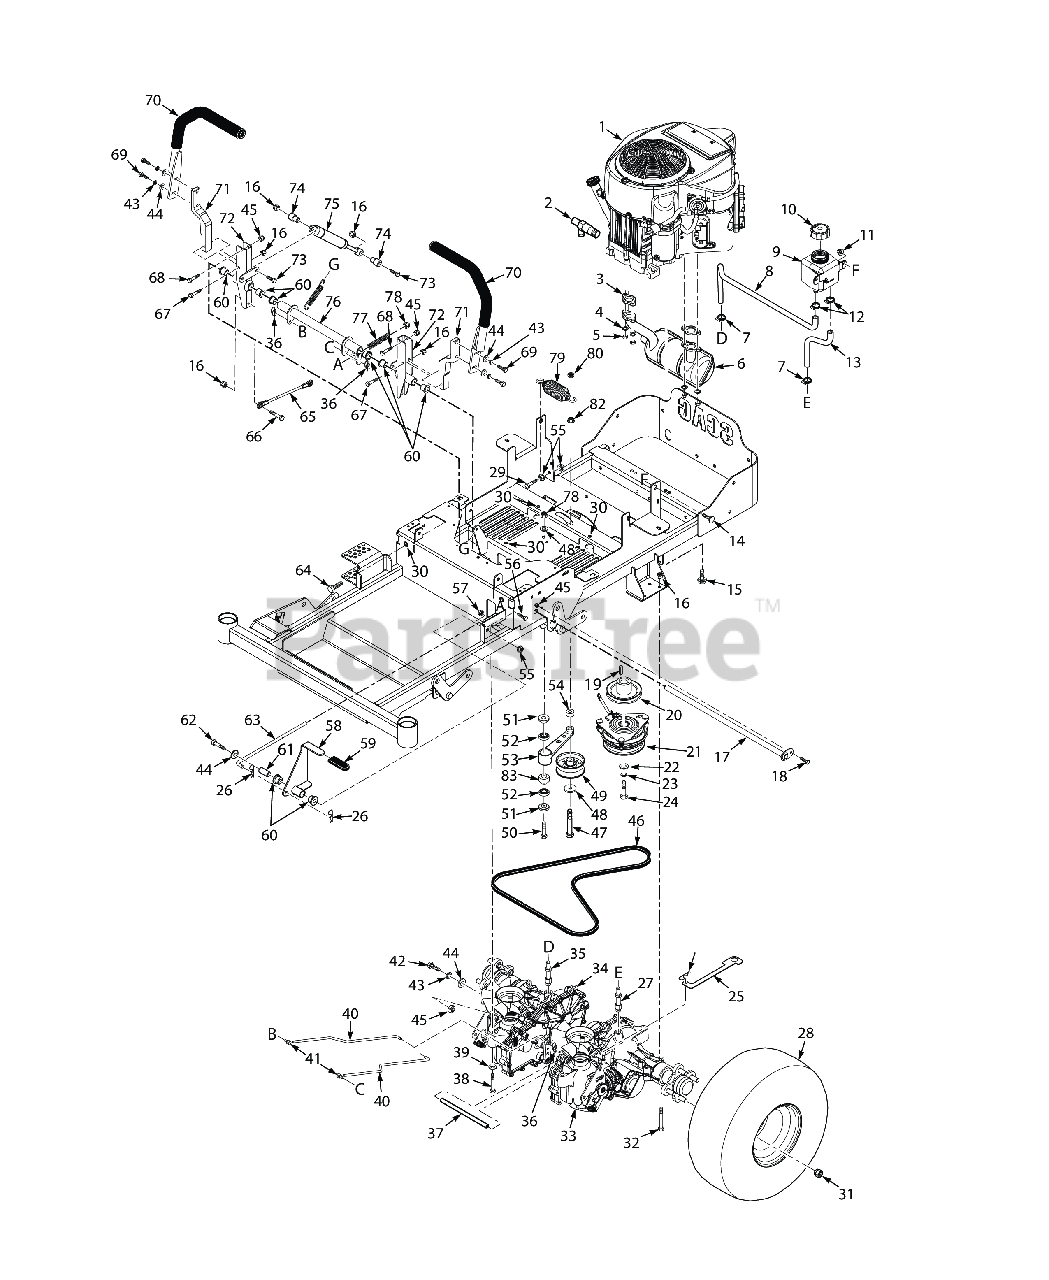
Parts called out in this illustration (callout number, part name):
1	Engine, Kawasaki - FR600V
2	Oil Drain, Kawasaki
3	Gasket, Exhaust
4	Nut, M8 x 1.25 Hex Special
5	Lockwasher, M8 Spring (Kawasaki)
6	Muffler, Kawasaki FR/FS600V
7	Clamp, .69" Max. / .25" Min. Dia.
8	Hose, RH Transaxle
9	Reservoir Assembly
10	Cap, Hydraulic Tank
11	Nut, Flanged Elastic Stop 1/4-20
12	Clamp, Cable 3/4" I.D.
13	Hose, LH Transmission
14	Serr. Fl. Hex Head CPSCR, 1/4-20 x 3/4"
15	Bolt, Hex Head Self-Tap 3/8-16 x 1-1/4" (Kohler x3 - 25EFI, Kohler x4 - 29EFI)
16	HEX NUT, ELASTIC STOP LOCK, 5/16-18
17	Shaft Weldment, Control Arm
18	BOLT, HEX HEAD, 1/4-20 X 5/8
19	Key, 1/4 x 1/4 x 1.25" Pulley Mtg.
20	Pulley, 4-1/2" Dia. - 1" Bore
21	Electric Clutch Assembly
22	Flatwasher, 7/16-.469 x 1.75 x .25 (48, 52)
23	Lockwasher, 7/16� Spring
24	Bolt, Hex Head 7/16-20 x 3" w/t Patch
25	Lever, Dump Valve
26	HAIR PIN, .08 DIAMETER X 1-3/16"
27	Fitting, 9/16" O-Ring x 3/8" Hose
28	Wheel Assembly, 20 x 8.0-10
28	Rim W/Valve Stem 10 x 5.0
28	Tire, 20 x 8.0-10
29	Bolt, Hex Head 3/8-16 x 1-1/2" Grade 8 Black
30	Threaded insert, Hex Head (Pressed)
31	Wheel Nut, 1/2-20 x 13/16
32	Bolt, Hex Head, 5/16-18 x 2.75 Zinc.
33	Transaxle, LH- ZT-2800
34	Transaxle, RH- ZT2800
35	Fitting, O-Ring 9/16 Hose
36	Pin, Rue Cotter 3/8" Diameter
37	Spacer, Axle
38	BOLT, HEX HEAD, 5/16-18 X 2-1/4
39	Flatwasher, 5/16-.375 x .875 x .083 (35BV & 37BV-EFI)
40	Rod, Brake
41	Joint, Swivel
42	Bolt, Hex Head, 1/4-20 x 1-1/2"
43	Lockwasher, 3/8" Spring, Kawasaki FX / FS
44	Flatwasher, 3/8" Special (.391 x .938 x .105)
45	HEX, NUT, ELASTIC STOP LOCK, 1/4-20
46	Belt, Transmission SZL-36
47	Capscrew, Hex Head 3/8-16 x 3-3/4"
48	Flatwasher, 3/8 (.391 x .938 x .105 HD) Grade 8
49	Pulley, 3-1/2" Dia.
50	Bolt, Hex Head 3/8-16 x 3" - 52"
51	Spacer, Controls
52	BEARINGS, BALL, NEUTRAL RETURN
53	Trans. Idler Arm Assy. (Includes 24, 79)
54	Spacer, Idler Pulley - SFZ61
55	NUT, 3/8-16 SERRATED FLANGE HEX HEAD
56	Bolt, Hex Head 5/16-18 x 1-1/2" (Right Front Engine Mounting, Briggs and Kohler Only)
57	NUT, 1/4-20 SERRATED FLANGE HEX HEAD
58	Brake Lever Assembly, SZL-36
59	Grip, Brake Handle
60	Bearing
61	Pivot, Brake Lever
62	Capscrew, Hex Head 3/8-16 x 2-1/2"
63	Rod, Upper Brake Linkage
64	Bolt, Hex Head 3/8-16 x 3.0
65	Linkage Assembly, Steering
66	Bolt, 5/16 - 18 x 1 - 1/4" Hex Head
67	Bolt, Hex Head 5/16-18 x 1-1/2" - Front
68	Bolt, Hex Head, 1/4-20 x 1-1/4"
69	Bolt, Hex Head 3/8-16 x 1-1/4", Kawasaki FX / FS
70	Handlebar W/ Grip, SZL-36
71	Lever, Control Arm
72	Control Arm Weldment, SZL-36
73	Bolt, Hex Head 5/16-18 x 2-1/2" (x3) (35BV & 37BV-EFI)
74	Spacer, Pump Dampener
75	Damper, Steering
76	Bellcrank Assembly, Brake
77	Spring, Brake
78	HEX NUT, ELASTIC STOP LOCK, 3/8-16
79	Spring, Transmission Idler
80	Bolt, Hex Head 3/8-16 x 1" Ser. Flg.
81	Spring, Deck Latch
82	Nut, 3/8-16 Serrated Flange
83	Spacer, Bearing
